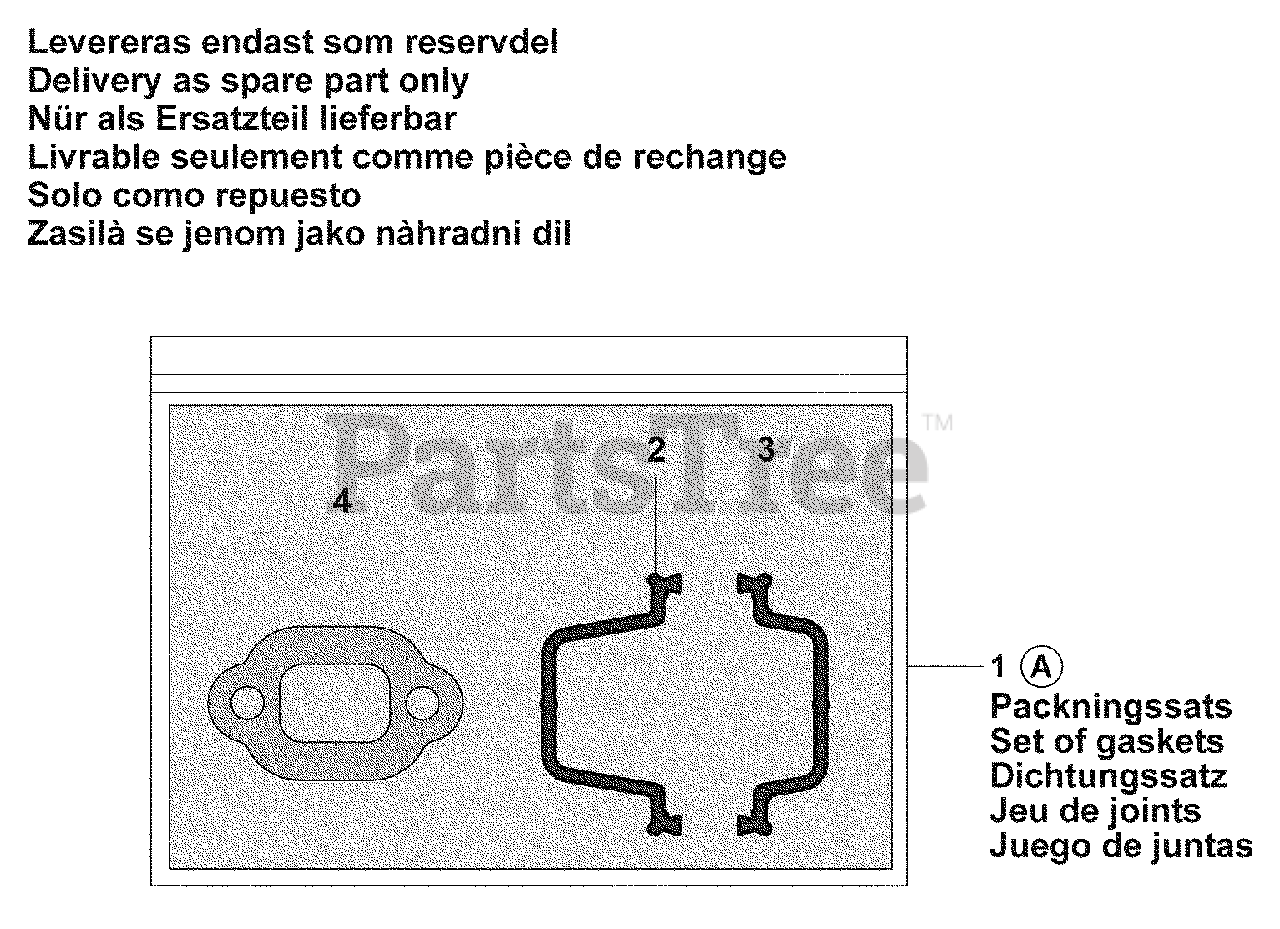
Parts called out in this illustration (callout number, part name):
1	Gasket Set
2	Cylinder Gasket, Front
3	Cylinder Gasket, Rear
4	Gasket
